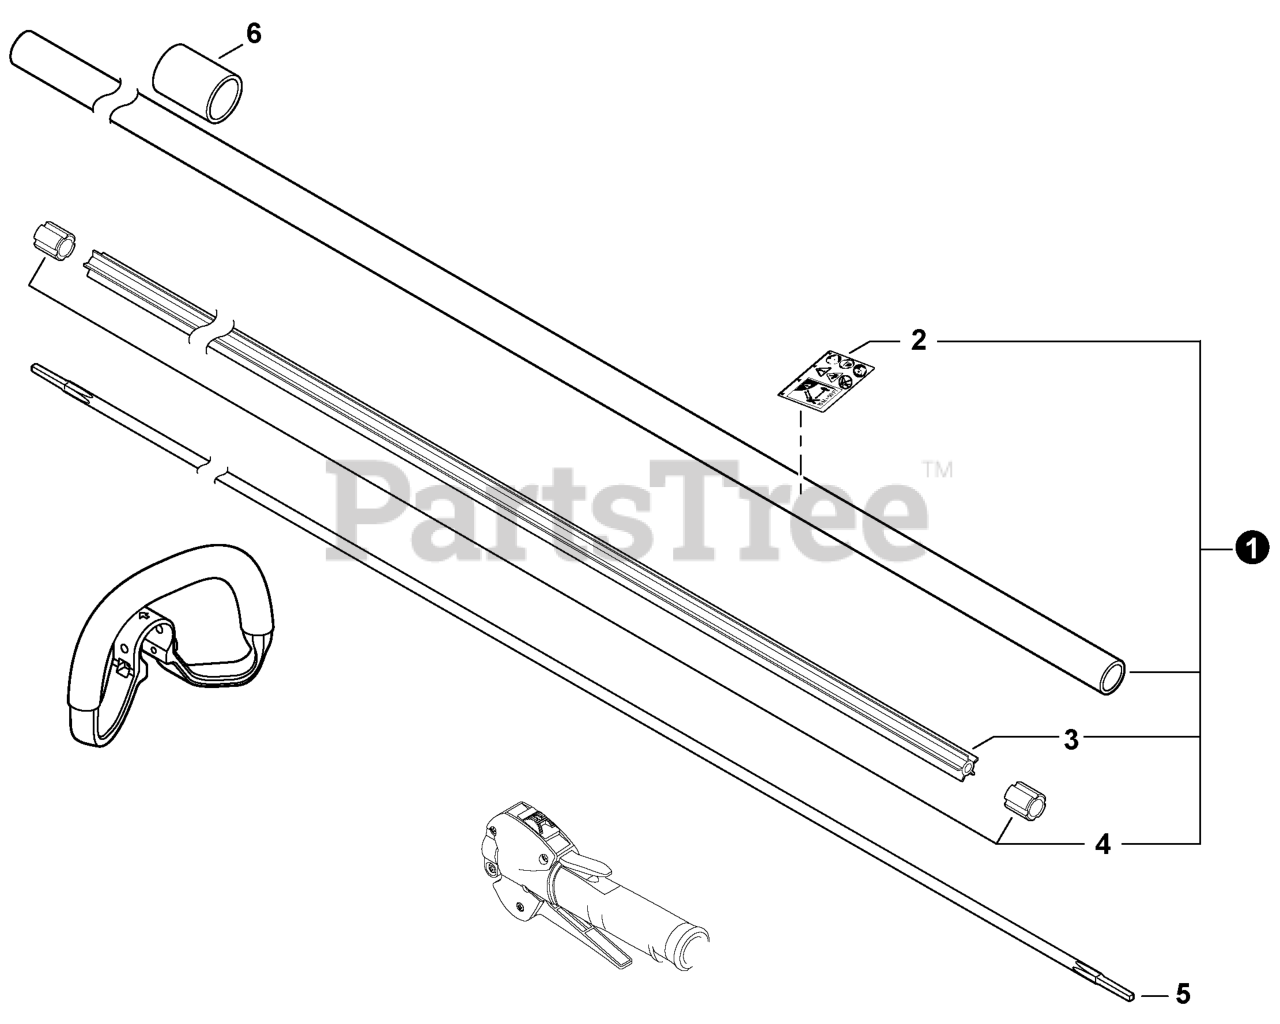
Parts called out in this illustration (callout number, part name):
1	MAIN PIPE ASSY
2	LABEL - CAUTION
3	LINER - FLEXIBLE
5	DRIVESHAFT - FLEXIBLE
6	COLLAR - 22
